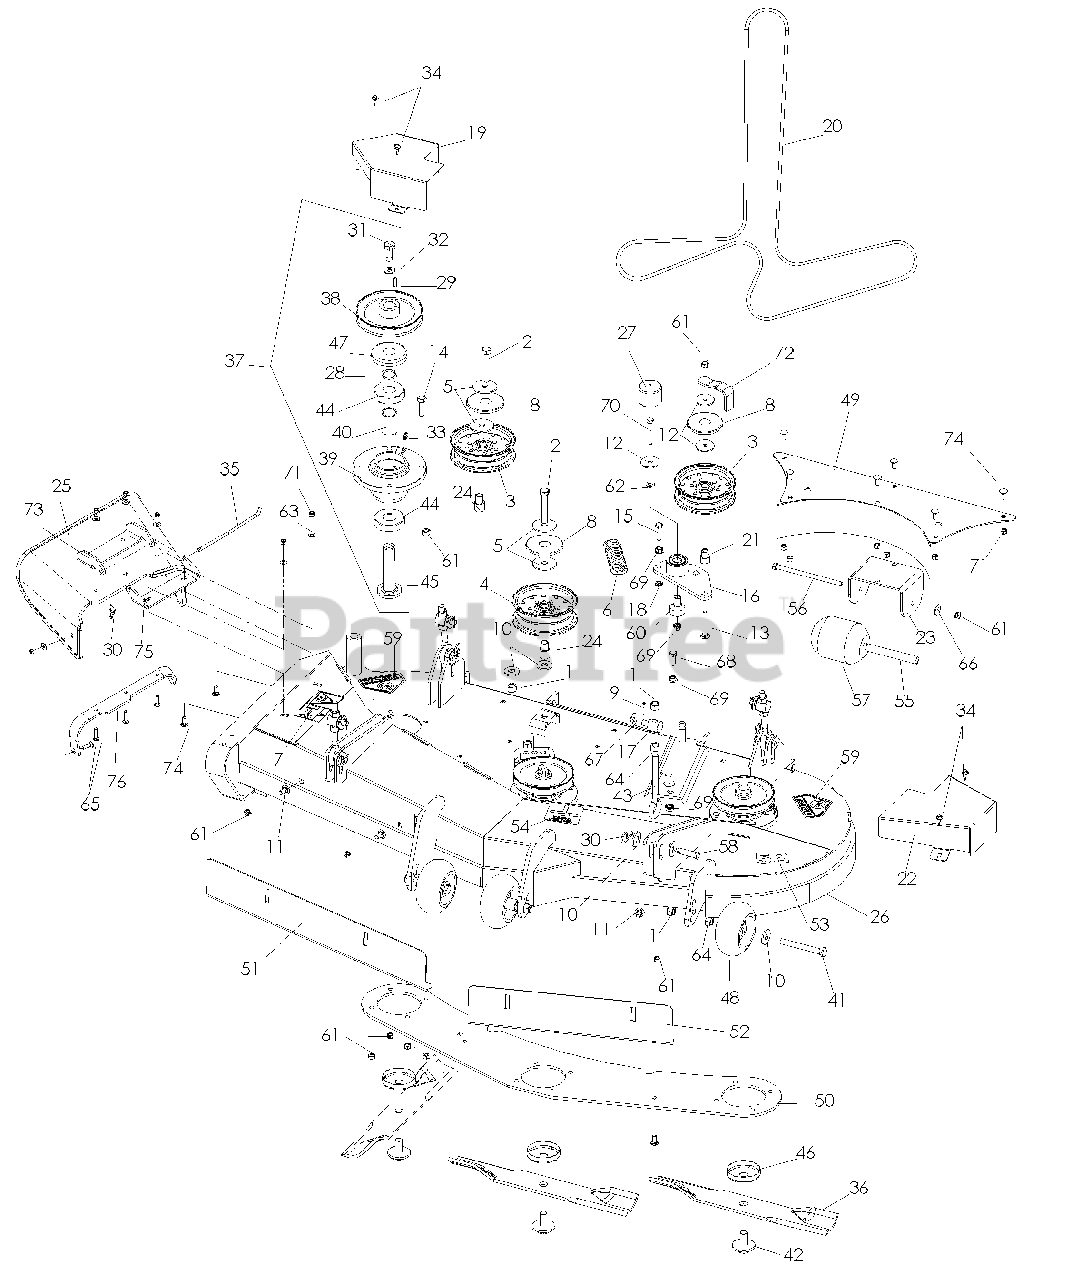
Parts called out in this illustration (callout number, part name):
1	NUT 1/2-13 HEX NYLOC ZD
2	SCREW, 1/2C X 3 HEX CAP
3	IDLER PULLEY
4	IDLER PULLEY (TALL)
5	ISOLATOR WASHER
6	DECK SPRING
7	DECAL, EURO SEVERING
8	TOP DUST CAP
9	PIN COTTER 1/8 X 1 ZD
10	WASH USS FLAT 1/2
11	RHSNB 3/8-16 X 3/4 GR5 ZD
12	WASHER, 3/8 SPEC
13	RHSNB 3/8-16 X 2.75
14	HCS 3/8C X 1 1/2
15	HCS 3/8-16 X 1-1/2
16	ARM-IDLER W/BRG
18	NUT 3/8-16 HEX JAM
19	PULLEY GUARD RH BLACK
20	BELT-DECK, 52
21	BUSHING, IDLER
22	PULLEY GUARD 52 LH BLACK
23	REAR CENTER ROLLER BKT 52 CLK
24	SPACER - IDLER
25	CHUTE, RUBBER DISCHARGE 52"
26	DECK W/DECAL 52 GRIZZLY
27	CAP, VINYL
28	HUB PULLEY SPACER
29	KEY - 1/4 X .88
30	PIN, COTTER 1 3/4
31	1/2-20 UNF X 1 1/4 HHBLT
32	WASHER .525 X 1.375 X .25
33	ZERK, 3/16, DRIVE IN
34	SCREW, TAP & DR #12-14 X 3/4
35	DEFLECTOR PIN
36	BLD 52HFS HI LIFT FUS
37	SPINDLE ASM.
38	METRIC PULLEY
39	DECK HUB MACHINED
41	HCS 1/2-13 X 4 GR 5 ZD
42	BLADE BOLT/WASHER
43	BOLT, EYE
44	BEARING - 6305 - 2RS
45	SHAFT SHORT
46	TRASH GUARD
47	TRASH GUARD
48	GAUGE WHEEL
49	W-BAFFLE WLDT.
50	HUB STIFFENER PLATE
51	BLOW-BY BAFFLE 52` LH
52	BLOW-BY BAFFLE 52` RH
53	DECAL, 52"
54	DECAL, BELT ROUTING (18656)
55	BUSHING
56	3/8-16 X 6-1/2 HHB GR8
57	ROLLER 3-3/4 DIA. X 4-1
58	CLEVIS PIN 1/2X1-3/4LG
59	DECAL, CPSC
60	PIVOT, BEARING
61	NUT 3/8-16 NYLOC
62	WASHER 3/8 SAE FLAT
63	FLAT WASHER 5/16 SAE
64	NUT HEX 1/2
65	RHSNB 5/16-18 X 1-1/2 GR 5 ZD
66	WASHER 3/8 FLAT
67	WASHER 1/2 FLAT
68	HCS 3/8C X 1
69	NUT 3/8C WHIZ
70	HCS 3/8C X 2 1/2
71	NUT 5/16 NYLOC
72	SLW 3/8 STD
73	PIVOT BRKT RUBBER CHUTE
74	RHSSNB 5/16C X 1.0
75	PIVOT BRACKET - DECK
76	BRACKET, REINF - CHUTE
